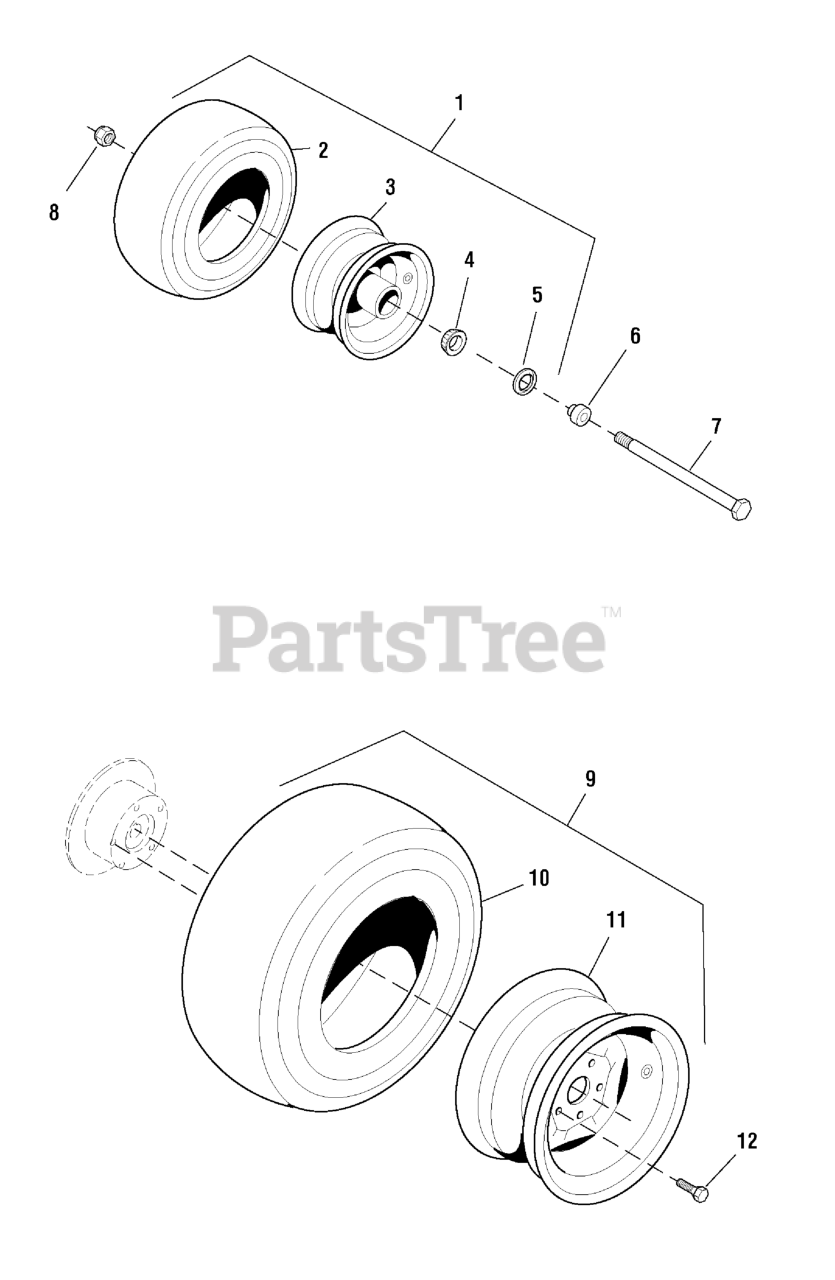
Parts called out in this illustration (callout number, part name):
1	WHEEL & TIRE ASSEMBLY, 13 x 5.0 x 6, Complete
2	TIRE, Front, 13 x 5.0 x 6
3	WHEEL ASSEMBLY, for 13 x 5.0 x 6 Tire, Complete
4	BEARING, Tapered Roller
5	SEAL, GREASE
6	ADAPTER, CASTER AXLE, CZ
7	BOLT, 1/2-13 x 7-1/2
8	NUT, 1/2-13 HEX NYLON LOCK
9	WHEEL & TIRE ASSEMBLY, 23 x 10.5 x 12, Complete
10	TIRE, Rear, 23 x 10.5 x 12
11	WHEEL ASSEMBLY, 12 x 8.5
12	WHEEL LUG, 1/2 x 1-5/8
